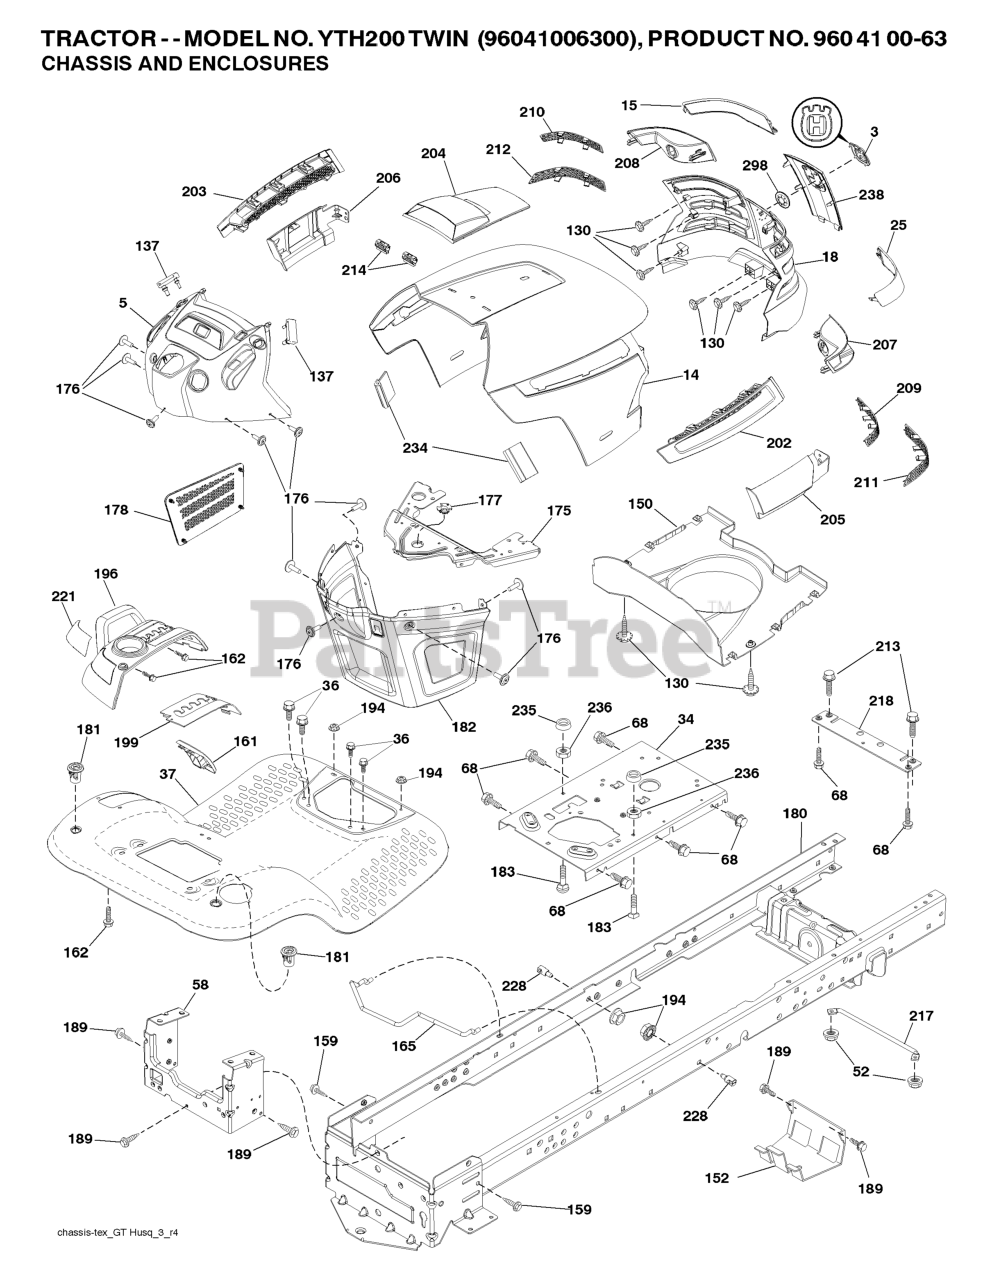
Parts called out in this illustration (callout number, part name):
3	RP LOGO
5	DASH.ASM.HUSQ.GT.E.RECT.W/CK
14	HOOD
15	LENS.LH.TEX.GT.HUSQ.CL
18	GRILL.ASM.HUSQ.TG/CRD.W/TRIM
25	LENS.RH.TEX.GT.HUSQ.CL
34	PLATE.ENGINE.WELDED.CHASSIS
36	SCREW 5/16"
37	FENDER.PNT.TX.GT.CH/FW.ORANGE
52	LOCKNUT
58	DRAWBAR.UPPER.2PC,LRG.FENDER
68	Screw 5/16-18 x 1/2 Hex, Self Tapping 5/16-18 x 1/2
130	SCREW
137	BUMPER DASH
150	AIR.DUCT.HOOD.TEX.GT.HUSQ
152	SHIELD.BROWNING.W/TEX
159	SCREW, 3/8-16X3/4
161	CONSOLE.FUEL.WINDOW.HU
162	SCREW.HI-LO.CONSOLE
165	SUPPORT.TANK.REAR.W/TEX
175	PLATE.CROSSMEMBER.HUSQ
176	SCREW.#10-24X5/8.RN.QU
177	BUSHING, STEERING
178	CARGO.ASM.NET.TXGT.W/C
180	CHASS.WLDMNT.TLT.12GA/2PC.20"
181	BUSHING.MNT.FEND.CRGO.
182	DASH.LOWER.COMMON.12V.ADAPTOR
183	BOLT.5/16-18X1-1/4 FULL.THREAD
189	SCREW
194	NUT LOCK HEX FLANGE 5/16-18
195	PLUG.HOLE.DASH.LOWER.12V.BLK
196	RP CONSOLE.ASM.DECKLFT.W/
199	PLATE.DECK.LIFT.HUSQVARNA.GT
202	VENT.SIDE.HOOD.HUSQ.RH.GREY
203	VENT.SIDE.HOOD.HUSQ.LH.GRAY
204	VENT.TOP.HOOD.HUSQVARN
205	SKIRT.HOOD.SIDE.HUSQ.RH.GREY
206	SKIRT.HOOD.SIDE.HUSQ.LH.GREY
207	BEZEL.RH.TEX.GT.HUSQ
208	BEZEL.LH.TEX.GT.HUSQ
209	INSERT.HEX.GRILL.HUSQ.GREY
210	INSERT.HEX.GRILL.HUSQ.
211	INSERT.HEX.GRILL.HUSQ.
212	INSERT.HEX.GRILL.HUSQ.
213	BOLT
214	CLIP.RETAINER.TINNER.
217	ROD.PIVOT.HOOD
218	X-PIECE.HOOD.STOP.NON/
221	REFLECTOR.LH.TEX GT HU
228	STUD.FASTNER.W/ANTI-ROTATE
230	SHOULDER BOLT 5/16-18TT
234	BUMPER.HOOD.TEX.HUSQVARNA
235	SPACER FENDER
236	NUT.CENTERLOCK.5/16-
238	TRIM.HUSQ.TG/CRD.SERVICE
239	NUT PUSH M
